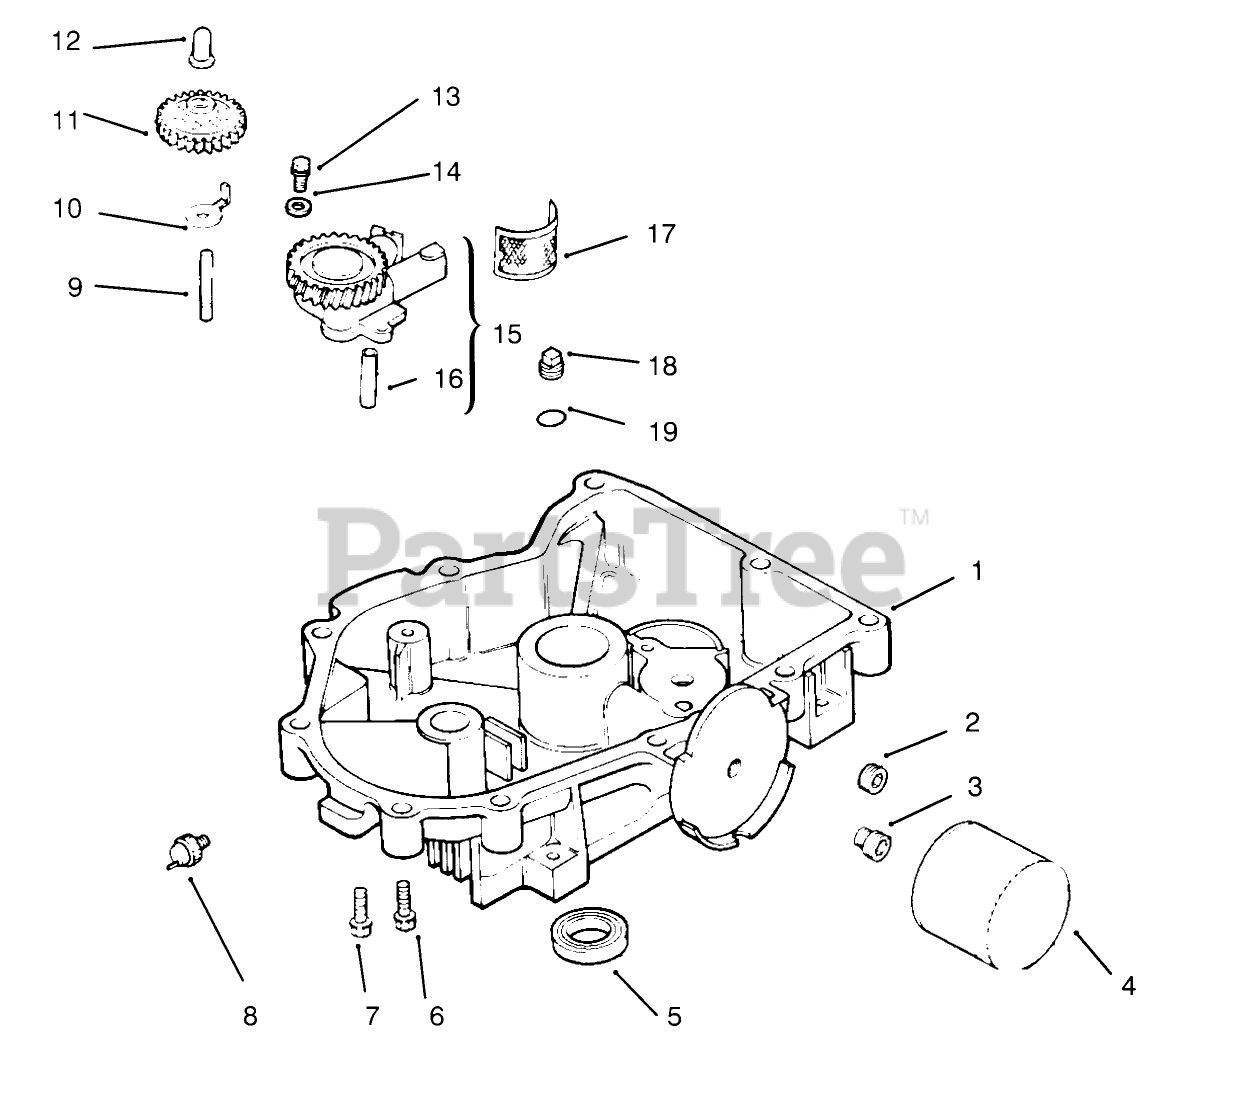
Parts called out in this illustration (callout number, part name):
1	Oil Pan (Only On: 72103)
2	Plug-HS 3/8 NPTF (Only On: 72103, 72083)
3	Nipple-Oil Filter
4	Filter-Oil
5	Seal-Oil
6	Screw M8x1.25x45 (Only On: 72103, 72083)
8	Switch-Oil Pressure
9	Shaft-Govenor Gear
10	Tab-Locking
11	Governor Gear ASM (Only On: 72103)
12	Pin-Governor
15	Oil Pump ASM INCL 16 (Only On: 72103)
16	Tube-Oil Pickup (Only On: 72103, 72083)
17	Screen-Oil Pickup (Only On: 72042, 72063, 72062, 72043)
